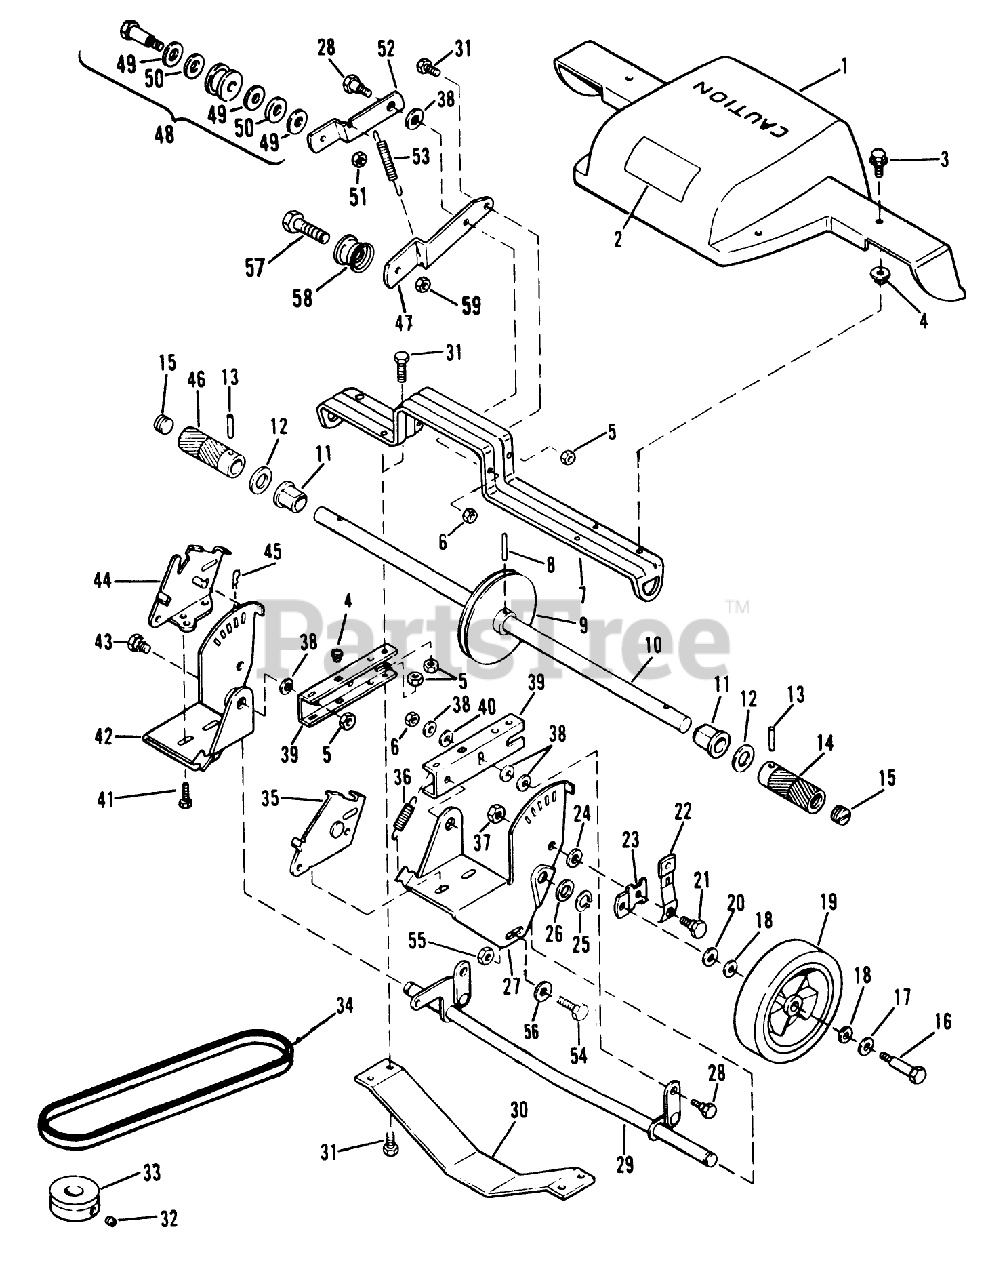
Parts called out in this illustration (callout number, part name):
1	COVER & DECAL AY
5	LOCKNUT E
6	STOP NUT
8	ROLL PIN
9	PULLEY
11	SLEEVE &BEARING AY
15	GREASE PLUG
16	BOLT WHEEL
17	SPACER
18	WASHER
20	WASHER WROUGHT
21	BOLT
22	KNOB&SPRING FORMCO
24	WASHER
25	RET RING
28	BOLT RB&W
32	SET SCREW F
33	PULLEY F
34	V-BELT
36	SPRING
37	LOCKNUT
38	WASHER S
41	SCREW
43	BOLT RB&W
45	HAIR PIN
46	R.H. DRIVE ROLLER
49	THRUST WASHER
51	NUT-LOCK F
55	NUT-LOCK F
58	PULLEY IDLER NHI
59	LOCKNUT
